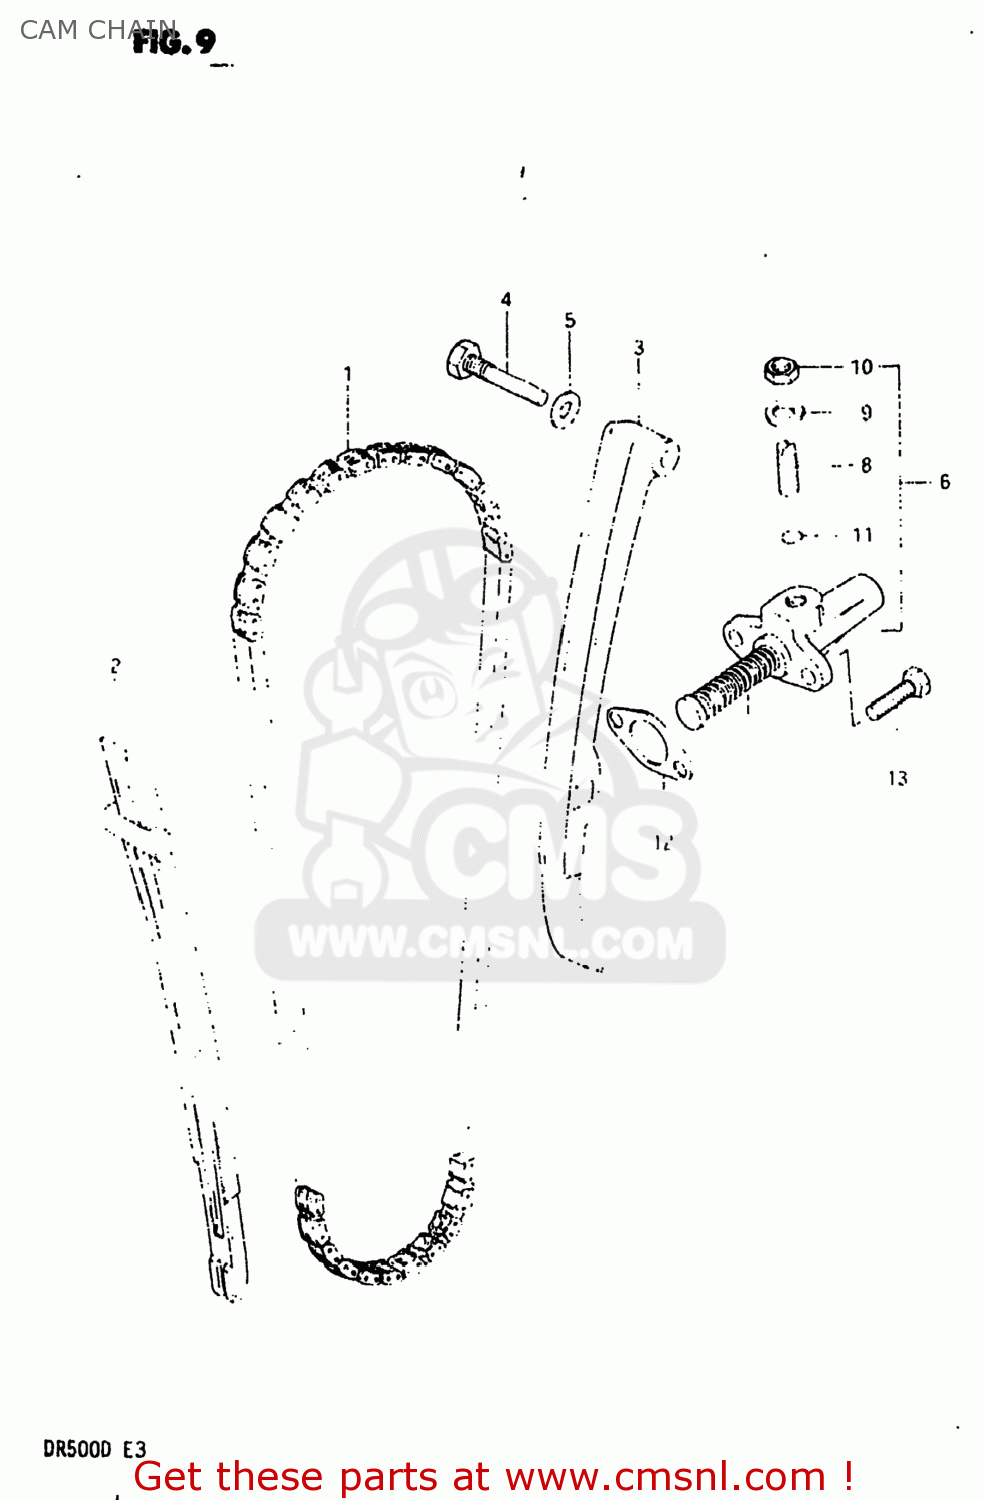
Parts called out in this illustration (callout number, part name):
1	CHAIN,CAMSHAFT DRIVE
2	GUIDE,CAM CHAIN
3	TENSIONER,CAM CHAIN
4	BOLT,CAM CHAIN TENSIONER
5	GASKET 8.2X14X1 (NAS)
6	ADJUSTER ASSEMBLY,TENSIONER
7	SPRING
8	SCREW
9	WASHER,8.5X16X
10	NUT
11	O-RING
12	GASKET,TENSIONER ADJUSTER (NAS)
13	BOLT
